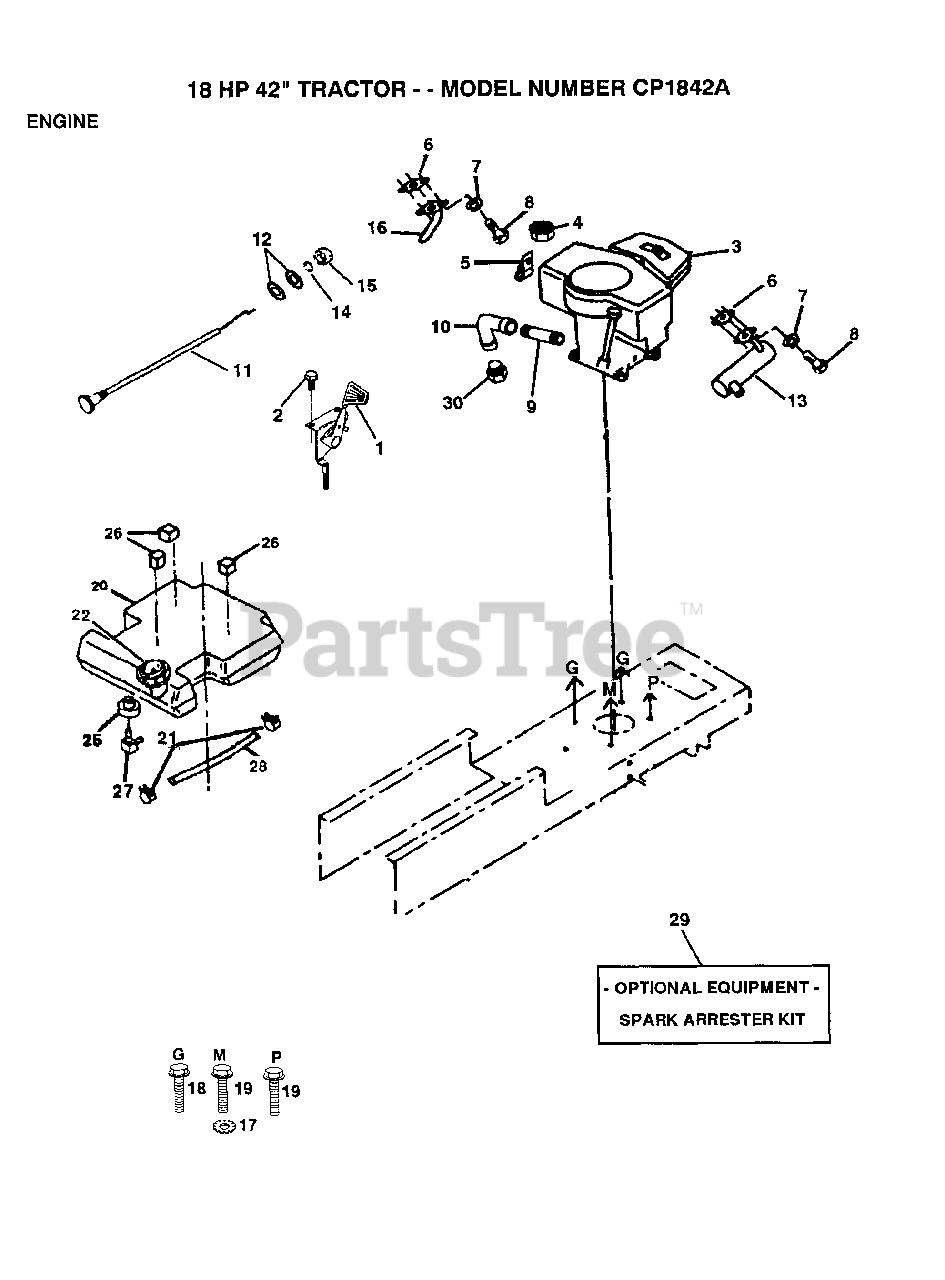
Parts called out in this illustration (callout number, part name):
2	SCREW LT
4	NUT
5	CLIP T
7	LOCKWASHER
9	PIPE NIPPLE LT
10	ELBOW
11	CHOKE CONTROL
12	WASHER
14	LOCKWASHER
16	EXHAUST TUBE T
17	LOCKWASHER
18	SCREW LT
19	SCREW LT
21	HOSE CLAMP
25	BUSHING OUTLET T
26	PAD-SPACER LT
27	FUEL TANK STEM GT
28	FUEL LINE T
